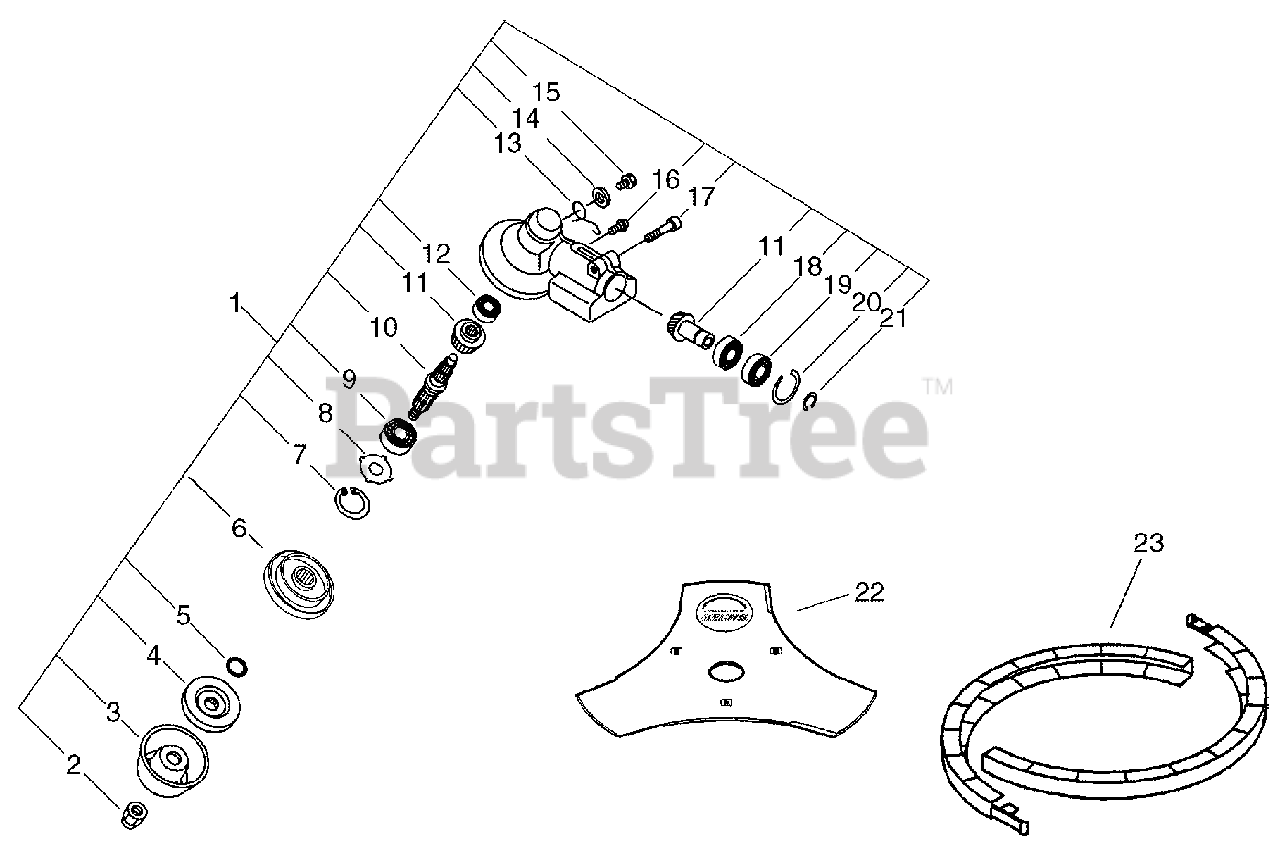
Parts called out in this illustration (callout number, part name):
1	CASE, GEAR
2	NUT - 10
4	ADAPTOR, BLADE - LOWER
5	O-RING - 12
6	BLADE ADAPTER KIT
7	RING, RETAINING - 32
9	BEARING, BALL - 6201
10	GEAR - SHAFT
11	GEAR SET
12	BEARING, BALL - 626
13	SPRING
14	WASHER - 8
15	BOLT - 8X8
16	SCREW - 5X10
17	SCREW - 6X25
18	BEARING, BALL - 6900
19	BEARING, BALL - 6900Z
20	RING, RETAINING - 22
21	RING, RETAINING - 10
22	BLADE, BRUSHCUTTER
23	COVER, BLADE
